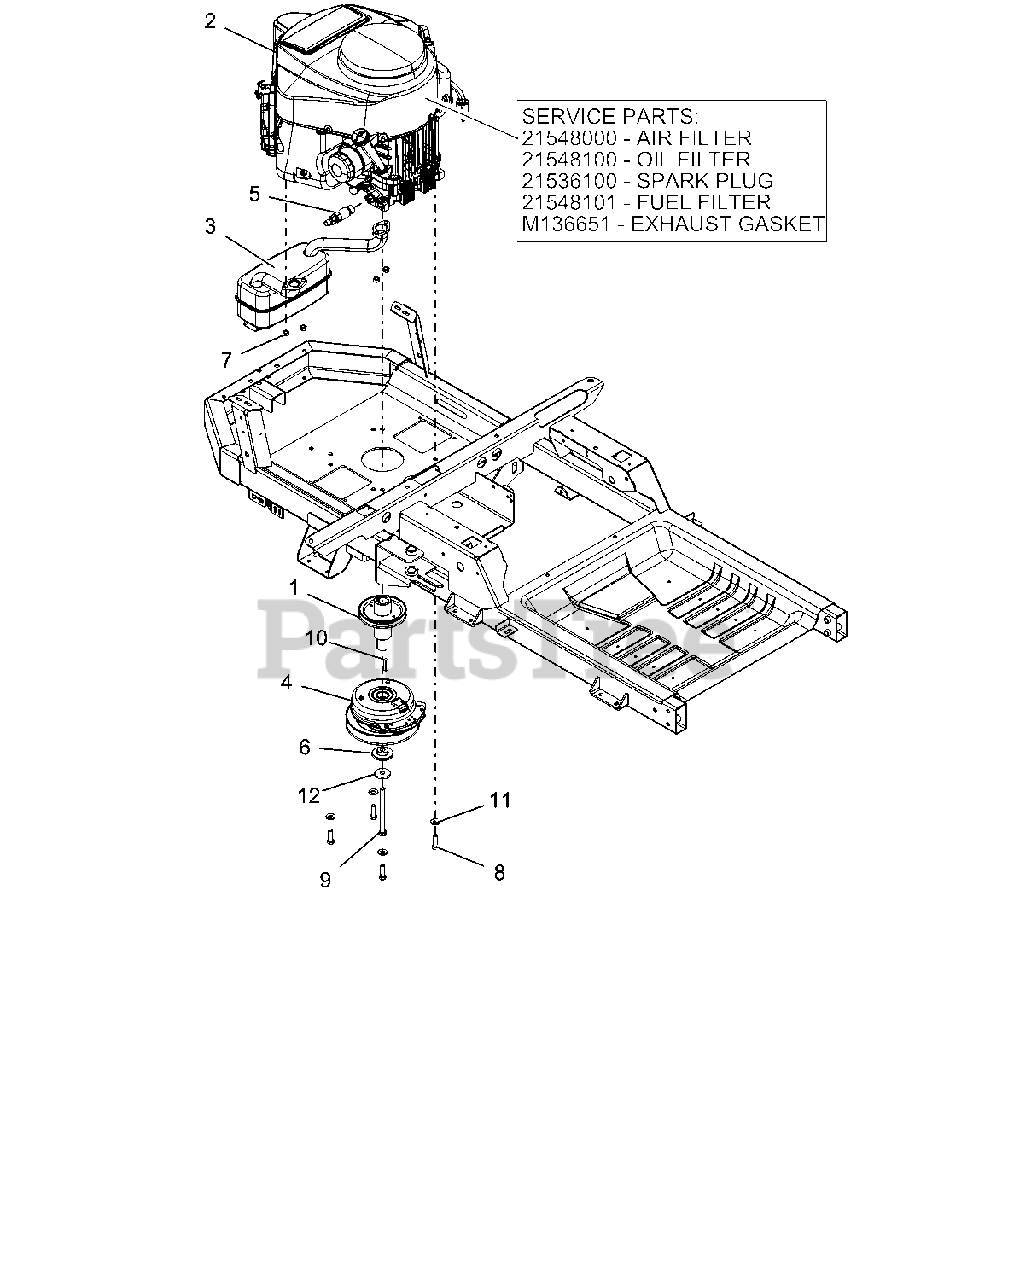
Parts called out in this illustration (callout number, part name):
1	WLDMT, DRIVE SHEAVE (LONG)
2	ENGINE, KAWASAKI FR651 21.5HP
2	AIR FILTER
2	OIL FILTER
2	SPARK PLUG
2	FUEL FILTER
2	EXHAUST GASKET
3	MUFFLER, KAWASAKI
4	CLUTCH, ELEC 105 FT LB MONOPOLE 6.83"
5	VALVE, DRAIN -M20X2.5
6	BSHG, -FLG .469 x 1.06 x .574 x 2.0
7	NUT-LK-TOP M8-1.25 YWZC
8	BLT-HEX .38-16X1.25 GR5 YWZC NYTORQ
9	BLT-HEX .44-20X5.00 GR8 YWZC NYTORQ
10	KEY-SQ .250X.250X1.250
11	WSHR, 3/8" SPRING DISC
12	WSHR, 7/16" SPRING DISC
